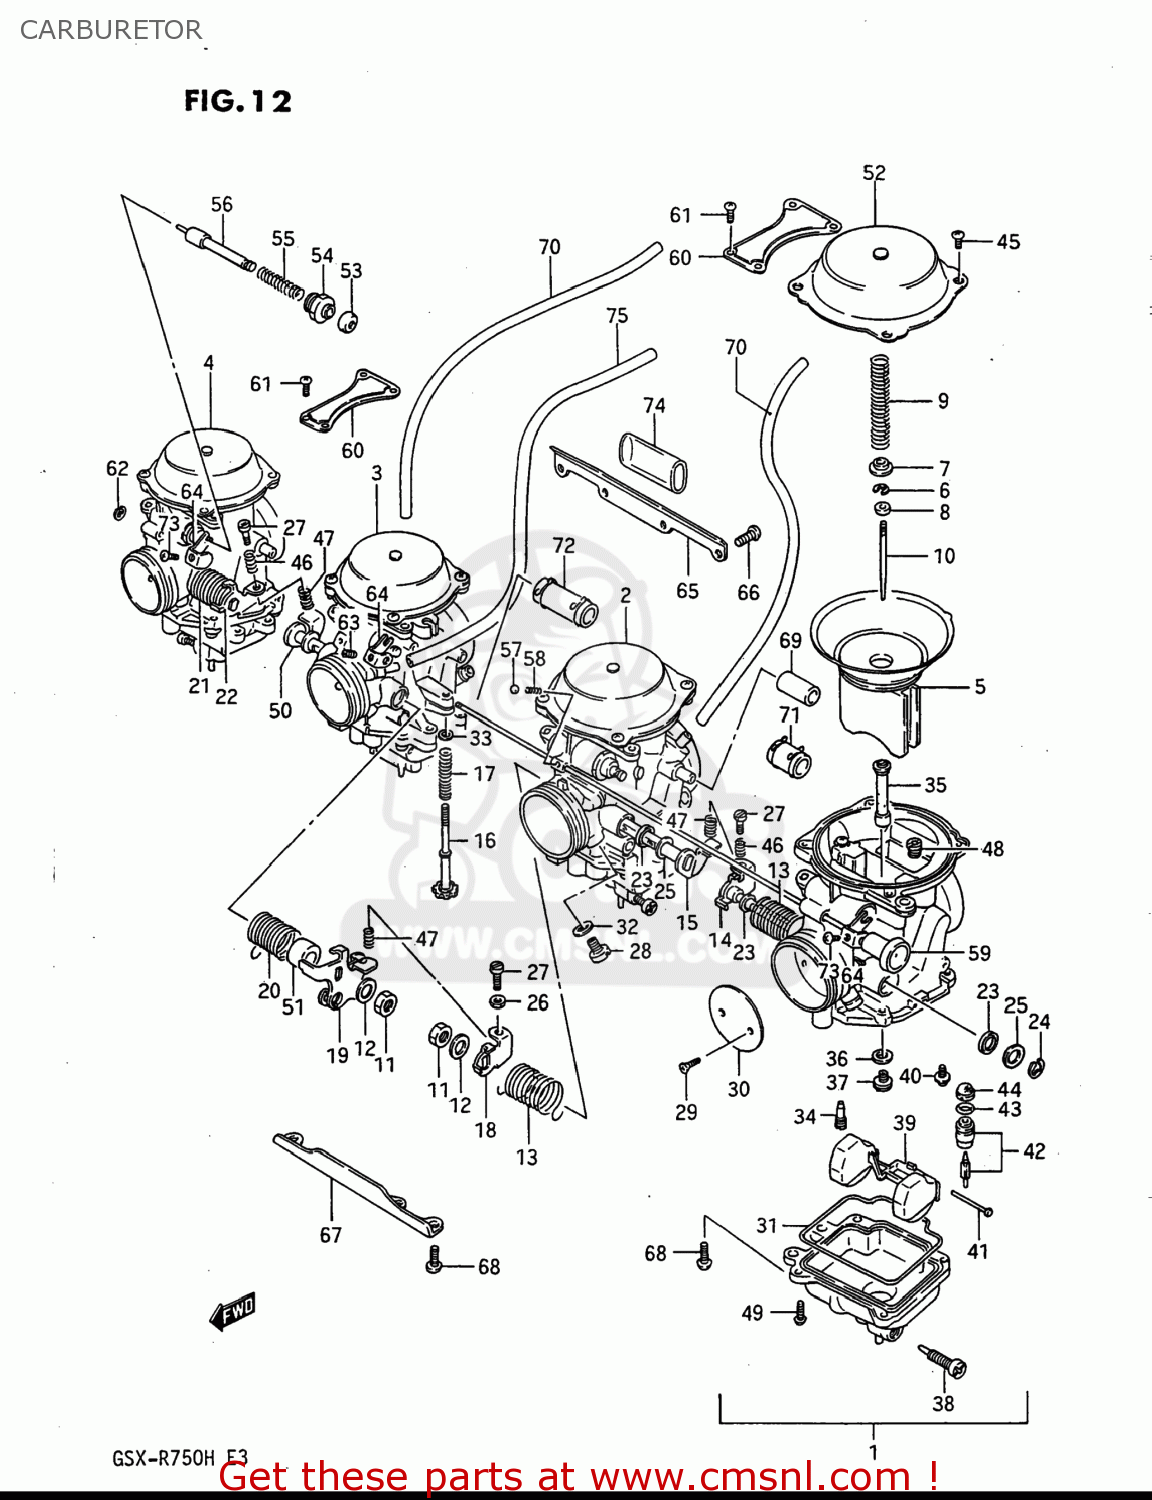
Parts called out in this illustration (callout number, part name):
1	CARBURETOR ASSEMBLY
2	CARBURETOR ASSEMBLY
3	CARBURETOR ASSEMBLY
4	CARBURETOR ASSEMBLY
5	DIAPHRAGM ASSY
6	CAP,LEVER
7	RING
8	RING
9	SPRING
10	NEEDLE,JET
11	NUT
12	WASHER
13	SPRING
14	SHAFT ASSEMBLY
15	SHAFT ASSEMBLY
16	SCREW
17	SPRING
18	LEVER
19	LEVER ASSEMBLY
20	SPRING
21	SPRING
22	SHAFT ASSEMBLY
23	SEAL
24	E RING
25	GASKET,THROTTLE SHAFT (NAS)
26	NUT,THROTTLE ROD
27	SCREW
28	SCREW
29	SCREW
30	VALVE,THROTTLE
31	O RING,FLOAT CHAMBER
32	WASHER
33	WASHER
34	JET,PILOT(35)
35	JET,NEEDLE(P-8)
36	WASHER,NEEDLE NOZZLE
37	JET,MAIN(117.5)
38	SCREW
39	FLOAT
40	SCREW
41	PIN,FLOAT
42	VALVE ASSY,NEEDLE
43	O RING
44	FILTER
45	SCREW
46	SPRING
47	SPRING,THROTTLE SCREW
48	JET
49	SCREW
50	SHAFT ASSEMBLY
51	RING
52	COVER,DIAPHRAGM
53	CAP,STARTER VALVE
54	GUIDE SCREW,PLUNGER
55	SPRING
56	PLUNGER ASSY
57	BALL,CARBURETOR
58	SPRING
59	SHAFT ASSEMBLY
60	PLATE
61	SCREW
62	E-RING
63	SCREW
64	LEVER
65	PLATE
66	SCREW
67	PLATE
68	SCREW
69	HOSE,CARBURETOR
70	HOSE
71	HOSE SET (3X5X18)
72	HOSE ASSY
73	SCREW
74	HOSE
75	HOSE
